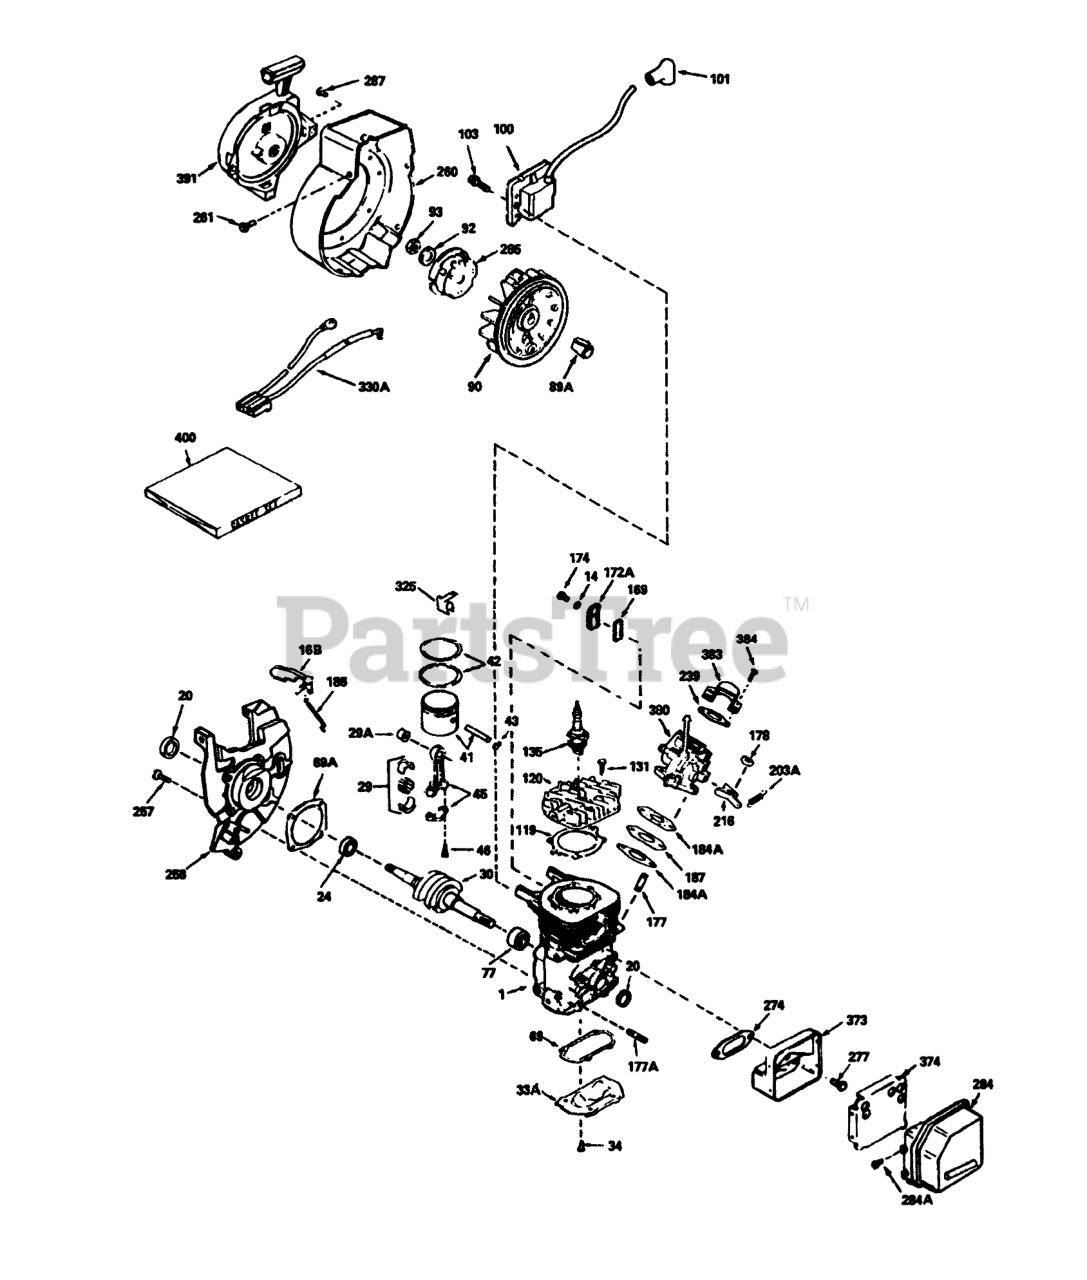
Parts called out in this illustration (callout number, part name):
1	Block Ass-y-Cylinder (Order short block if replacement is required)
16B	Vane-Air
20	Seal-Oil
24	Bearing-Ball
29	Needle Bearing and Liner Set (37 Needles)
29A	Bearing-Cartridge
30	Crankshaft
33A	Plate-Cover
34	Screw (T-25, 10-24 x 1/2)
41	Piston & Pin Ass-y (Incl. Ref. #43)
42	Ring Set
43	Ring-Retaning
45	Rod Ass-y-Connecting (Incl. Ref. #29, 29A, & 46)
46	Bolt-Rod, Connecting
69	Gasket-Plate, Cover
69A	Gasket-Cover, Cylinder
77	Bearing-Cartridge
89A	Blade (20 inch)
90	Flywheel
92	Washer-Belleville
93	Nut-Flywheel
100	Solid State
101	Cover-Spark Plug
103	Screw
119	Gasket-Head, Cylinder
120	Head-Cylinder
131	Screw (T-30, 1/4-20 x 3/4)
135	Spark Plug-Resistor (R C J 8Y)
169	Cover-Compression, Release
172A	Comp. Release Cover
174	Screw (T-25, 10-24 x 1/2)
178	Locknut
184A	Gasket-Carburetor
186	Link-Governor
203A	Spring-Governor
216	Lever-Adjusting, Rpm
239	Gasket-Cleaner, Air
257	Screw (T-30, 1/4-20 x 5/8)
258	Base Ass-y-Blower Housing (Incl Ref. #20)
260	Housing-Blower
261	Screw (1/4-20 x 1/2)
274	Gasket-Exhaust
277	Screw (T-30, 1/4-20 x 5/8)
284	Cover-Muffler
285	Cup-Starter
287	Rivet-Pop
325	Clip-Wire
330A	Harness-Wire
373	Base-Muffler
374	Baffle-Muffler
380	Carburetor (Incl. Ref. #184A)
383	Baffle-Carburetor
391	Starter-Rewind
400	Gasket Set
